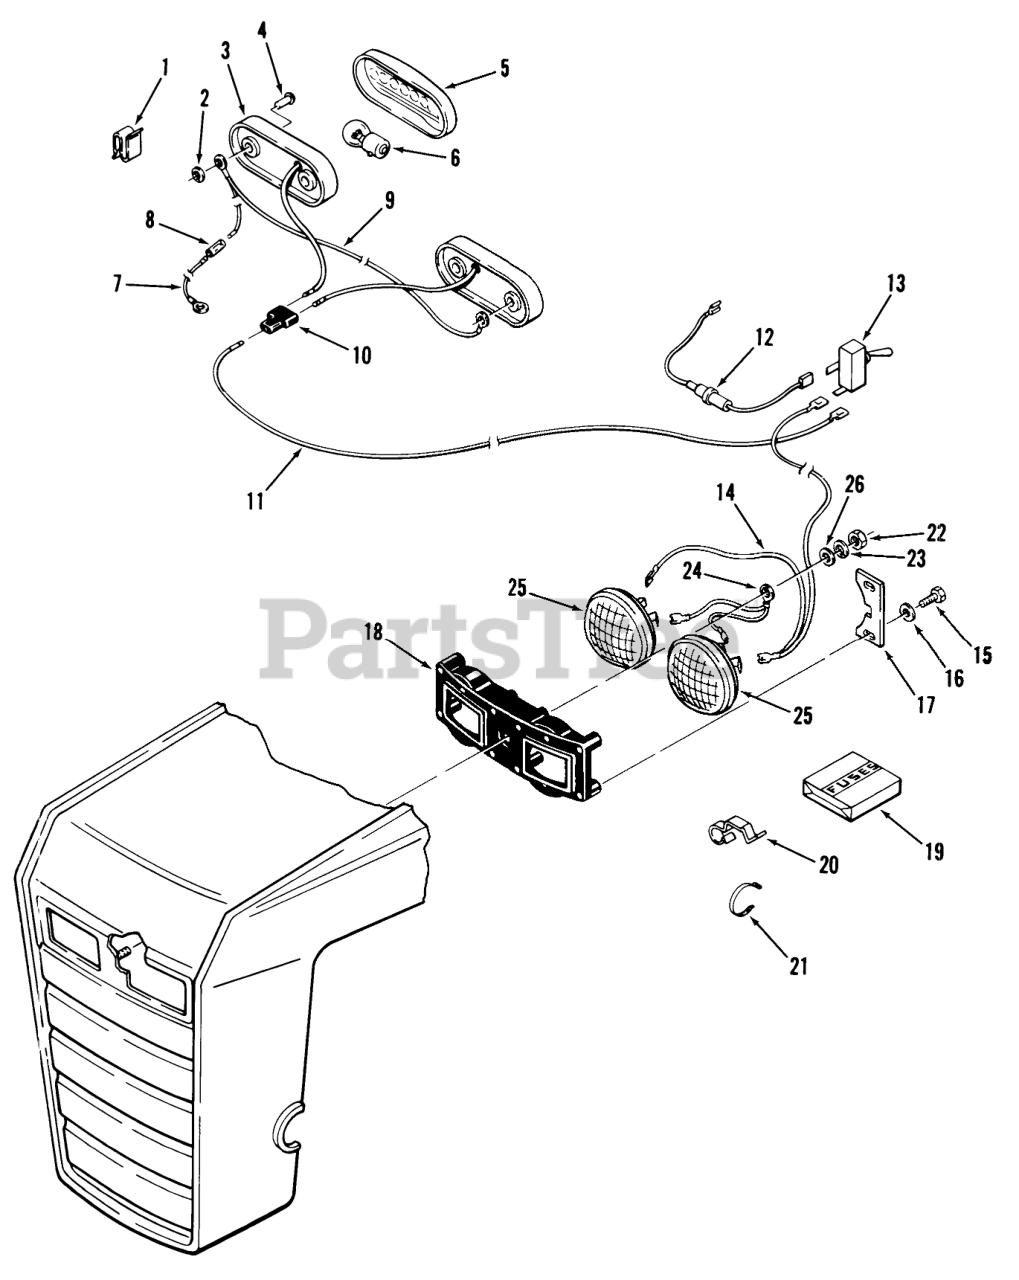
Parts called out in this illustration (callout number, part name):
1	SPEED CLIP
2	WASHER
3	BASE-TAIL LIGHT
4	Pop Rivet
5	Lens-Taillight
6	Bulb
7	ASSEMBLY-WIRE
8	CONNECTOR 2 WIRE
9	Taillight Wire
10	CONNECTOR 3 WIRE
11	Taillight Wire C-165, C-175 Only
12	ASSY FUSED CONNECTOR
13	SWITCH-LIGHTS
14	WIRE-HEADLIGHTS
15	SCREW
17	Clamp
18	Headlight Retainer
20	CLIP-WIRE
21	PLASTIC TIE
22	Nut
23	Washer-Lock
24	LIGHT GROUND WIRE
25	HEADLAMP
26	WASHER 5/16 SAE
